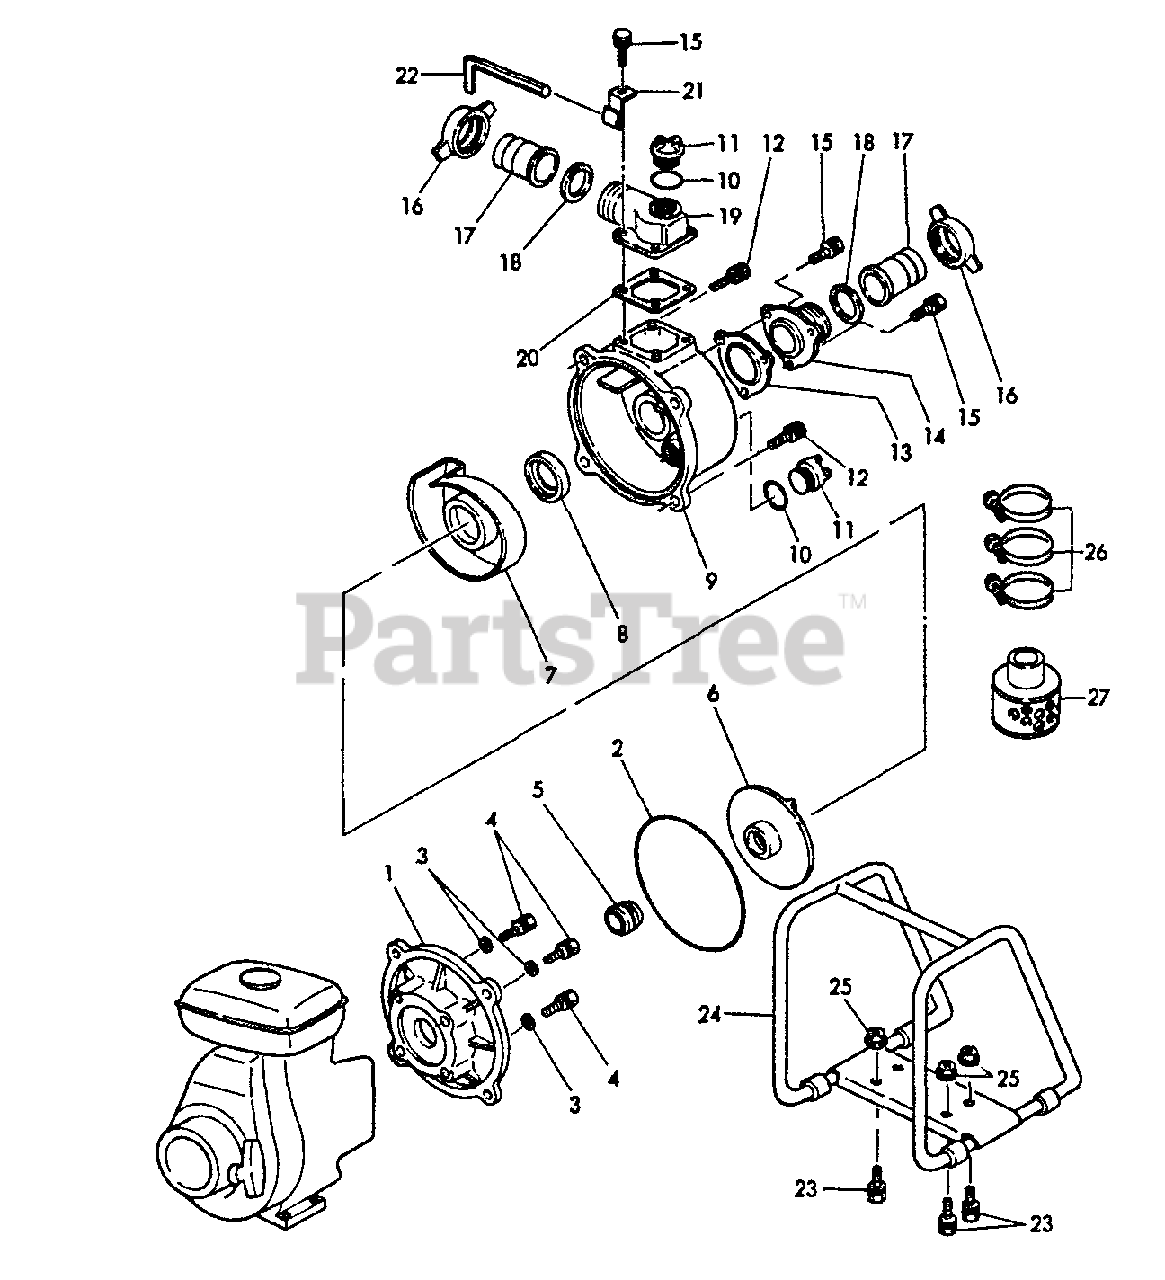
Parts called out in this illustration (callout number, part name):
1	COVER, PUMP CASE
2	GASKET, CASING
3	GASKET, SEAL
4	BOLT - 8X48
5	SEAL
6	IMPELLER, Shim 0.5 Y50106100000
7	CASING, INNER, Shim 0.8 Y50106200000
8	GASKET, INNER CASING
9	CASING
11	PLUG, PRIMING
12	BOLT
13	VALVE, CHECK
14	CASE (NPT), VALVE
15	BOLT - 8X25
16	JOINT, HOSE
17	COUPLING, HOSE
18	GASKET, COUPLING
19	BEND (NPT), DELIVERY
20	GASKET, BEND
21	HOOK
22	HEX KEY
23	BOLT
24	FRAME
25	NUT - FLANGE
26	BAND, HOSE
27	STRAINER, DEBRIS
